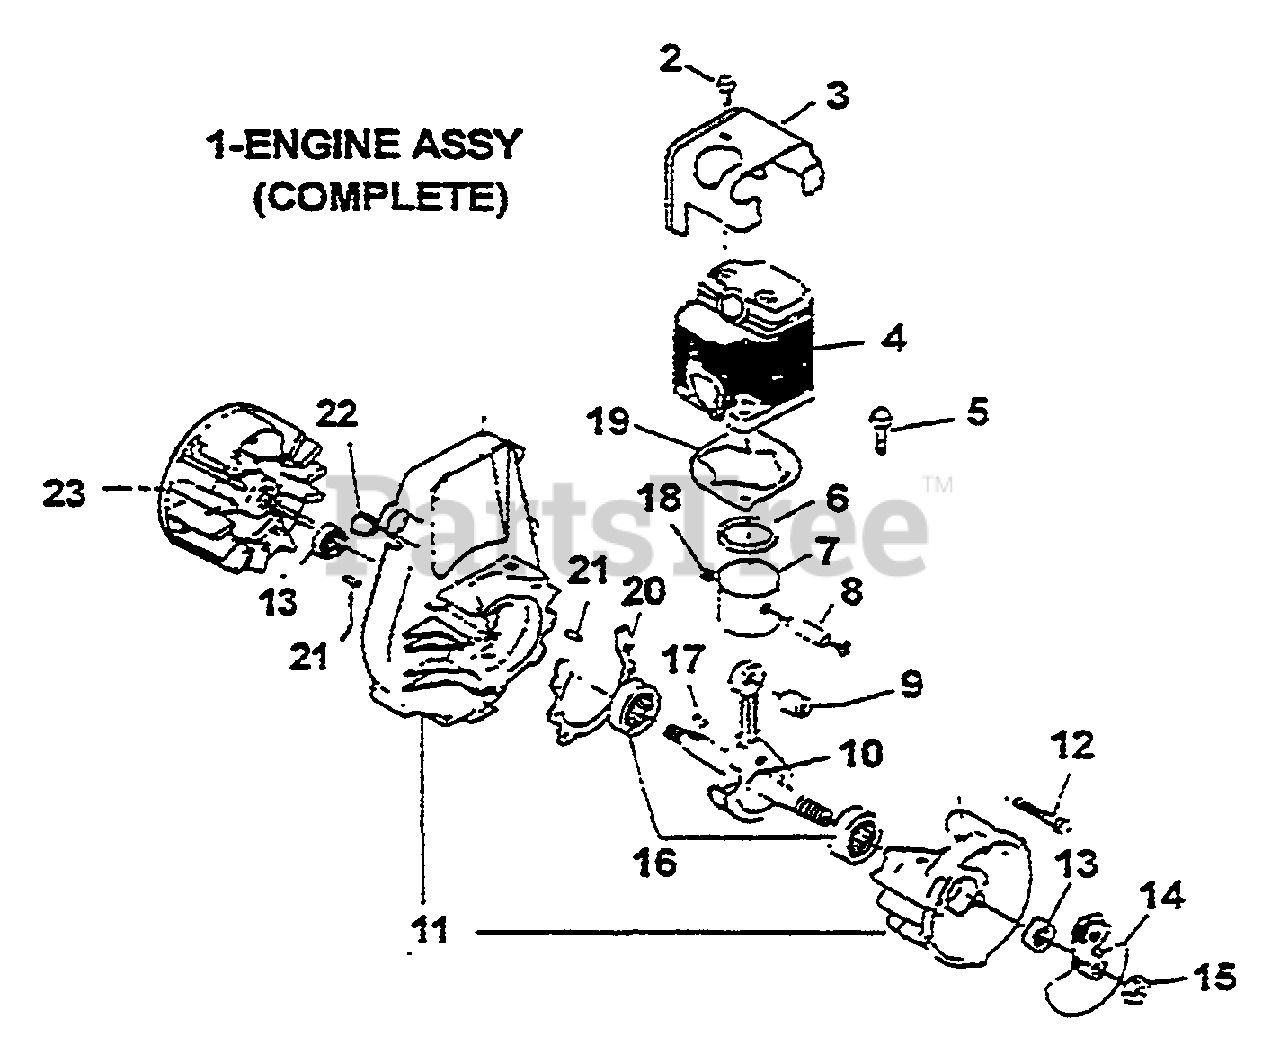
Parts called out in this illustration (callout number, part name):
1	ENGINE ASSY
3	COVER, CYLINDER
4	CYLINDER
6	RING, PISTON
7	PISTON
8	WRIST PIN
10	CRANKSHAFT ASSY
11	CRANKCASE ASSY
14	RATCHET ASSY
17	KEY, FLYWHEEL
18	SNAP RING
19	GASKET, CYLINDER
20	GASKET, CRANKCASE
